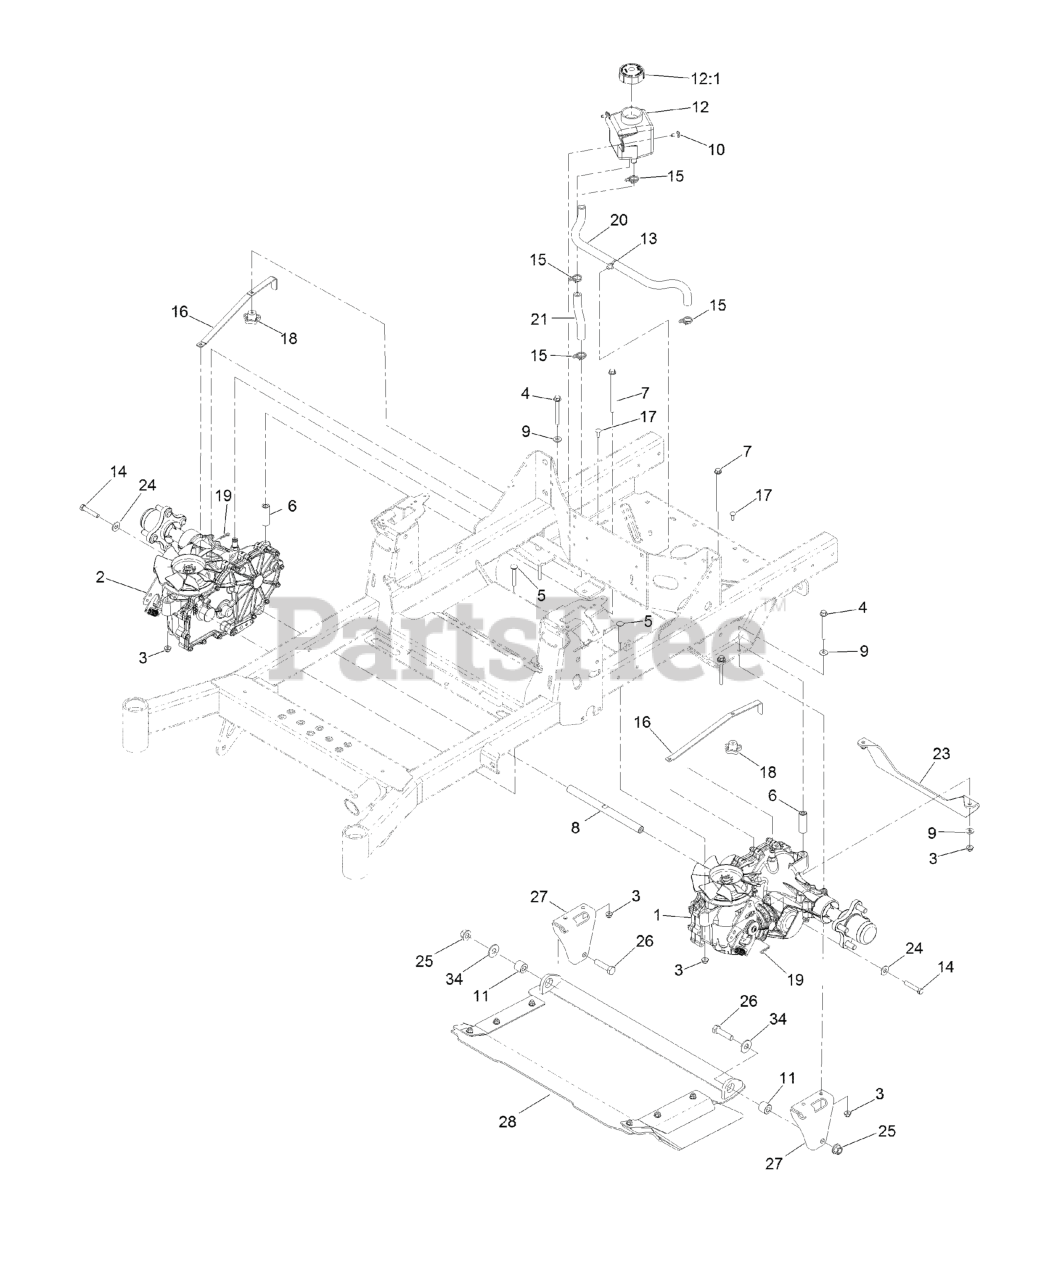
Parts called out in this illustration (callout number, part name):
1	LH TRANSAXLE ASM
2	RH TRANSAXLE ASM
3	NUT-HF, NI
4	SCREW-HHF
5	BOLT-CARR
6	SPACER-HYDRO
7	SCREW HHF
8	SHAFT-SPACER
9	WASHER-SPRING
10	SCREW-TORX
11	BUSHING-SLEEVE
12	TANK-HYD
12:1	CAP-RESERVOIR, HYD
13	CLIP-TIE
14	SCREW-HH W/LOCTITE
15	CLAMP-HOSE
16	ARM-BYPASS, HYDRO
17	BOLT-CARR
18	KNOB-HANDLE
19	PIN-COTTER
20	HOSE-HYDRAULIC
21	HOSE-HYDRAULIC
23	SUPPORT-TRANSMISSION
24	WASHER-FLAT
25	Nut-Lock 1/2-13
26	SCREW-HH
27	BRACKET-MOUNT, DISCHARGE
28	DISCHARGE TUNNEL ASM
34	WASHER-FLAT
